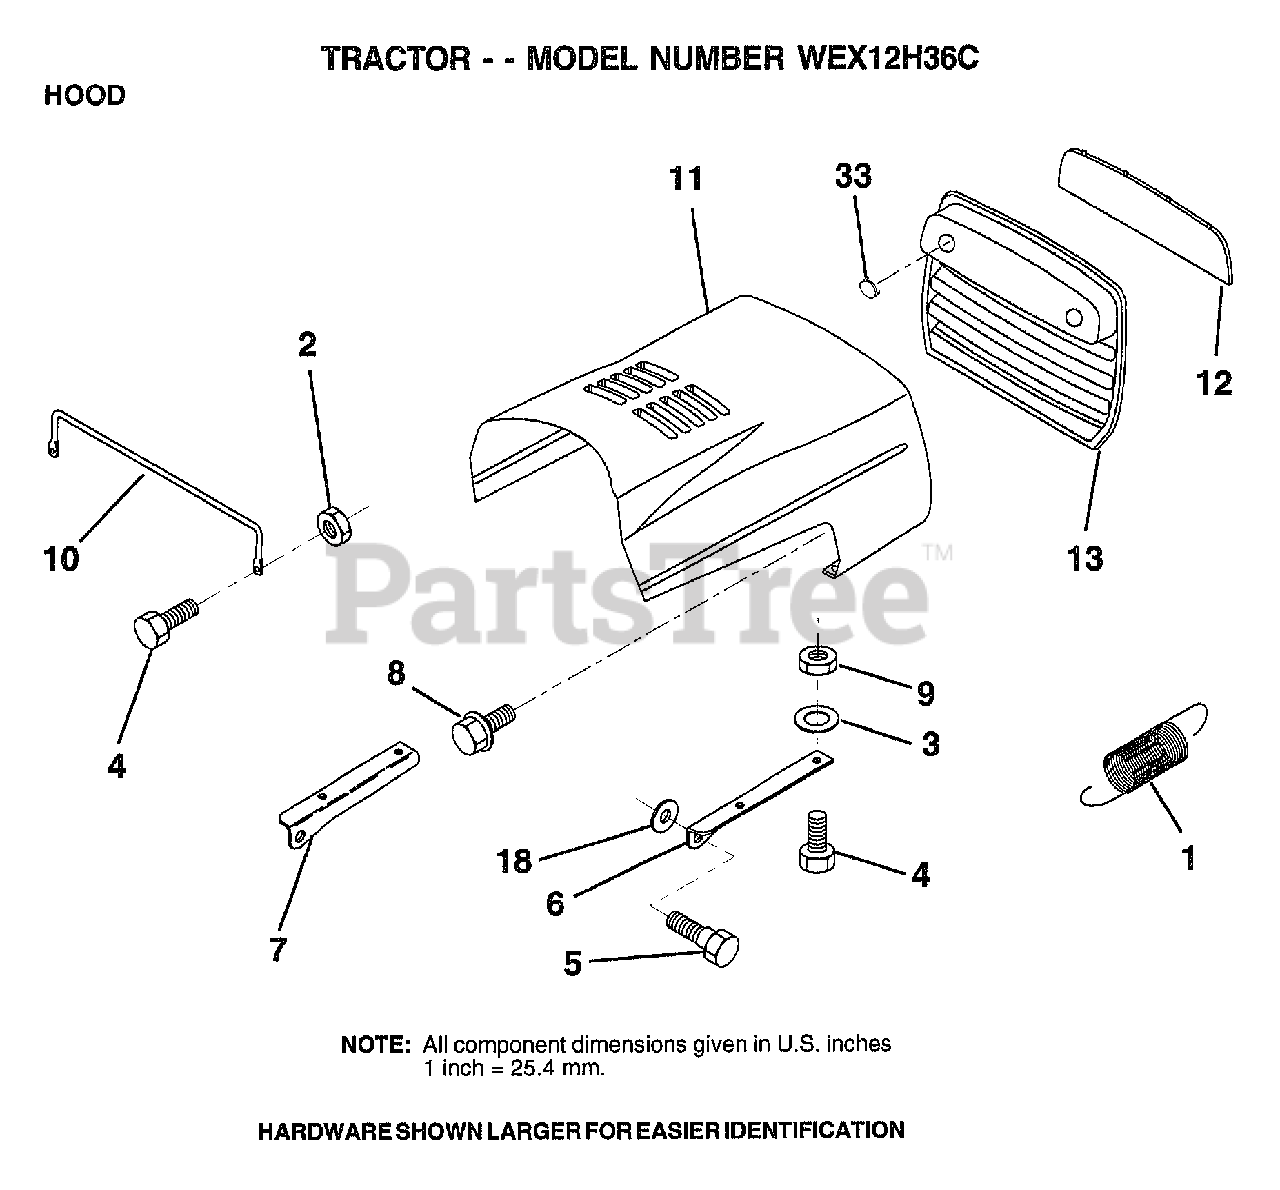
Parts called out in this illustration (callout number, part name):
1	EXT SPRING
2	NUT
3	WASHER
5	BOLT.SHLD.5/16-18
6	BRKT HOOD RH
7	BRKT HOOD LH
8	"SCREW,HWHD.HI-LO#13-16X3/4"
9	NUT
10	"BRACE,HOOD"
11	HOOD.IMPREG.MS550
12	LENS
13	GRILL
18	WASHER
